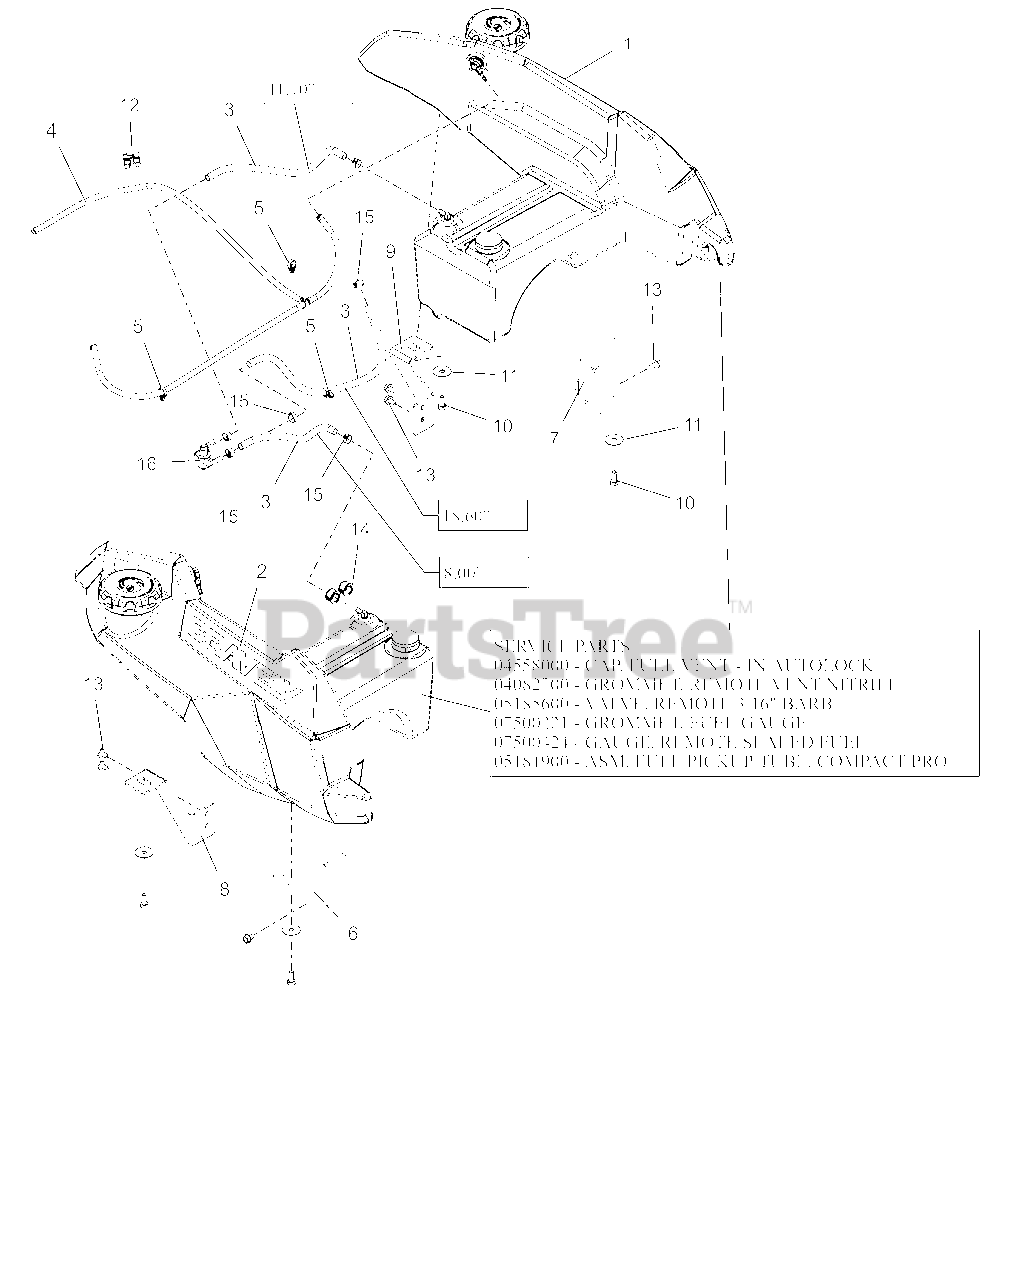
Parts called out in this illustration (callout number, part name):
1	ASM, COMPACT PRO FUEL TANK
2	TANK, RH COMPACT PRO FUEL
2	CAP, FUEL VENTIN AUTOLOCK
2	GROMMET, REMOTE VENT NITRILE
2	VALVE, COMBINATION VENT 3/16
2	GROMMET, FUEL GAUGE
2	GAGE, FUEL
2	ASM, COMPACT PRO FUEL PICKUP
3	HOSE, .25 LOW-PERM BULK GAS
4	ASM, COMPACT PRO VAPOR LINE
5	ROUTING CLIP (1/2" ID)
6	BRKT, RH FRONT MTG
7	BRKT, LH FRONT MTG
8	BRKT, RH REAR MTG
9	BRKT, LH REAR MTG
10	BLT,HEX .31-18X.75 G5 ZCC
11	WSHR, FLT .347X1.254X.048 ZCC
12	CLIP, T, .38-.50
13	SCR,TAP .312-18X.50 HWH TR ZCC
14	BUSH, PANEL SNAP .687X.875X.56
15	CLAMP, FUEL LINE
16	VALVE, FUEL
